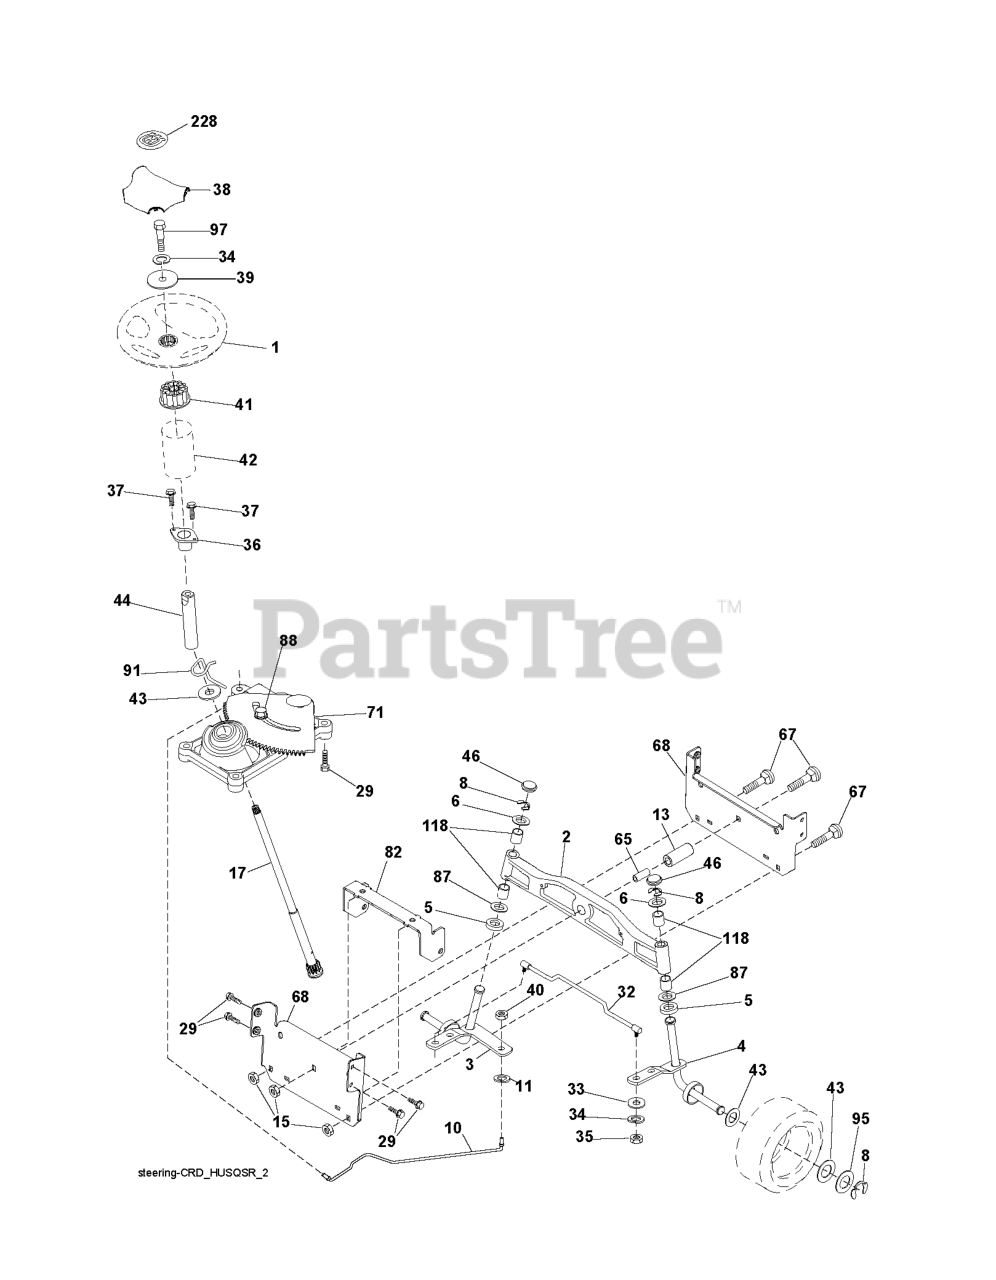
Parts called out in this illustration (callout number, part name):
1	RP WHEEL.STEER.HUSQ.PREM.OVMLD
2	AXLE ASSY FRONT
3	SPINDLE.ASM.LH.15"TIRES
4	SPINDLE.ASM.RH.15"TIRES
5	THRUST WASHER
10	DRAGLINK.15".TIRES.2001
11	WASHER, LOCK 3/8
13	TUBE, PIVOT AXLE
15	NUT
17	SHAFT STEERING SPLINE
29	SCREW, 3/8-16X3/4
33	WASHER M
34	WASHER.LOCK.HVY.HLCL.SPR.5/16
35	NUT, CROWNLOCK
36	BUSHING, STEERING
37	SCREW.TT.#10-32X.5.3/8.FLANGE
38	RP INSERT.CAP.WHL.STRG.HUSQ.
39	WASHER.11/32
40	NUT CROWNLOCK 3/8-24
41	ADAPTER, WHEEL STNG..
42	BOOT, STEERING
44	SHAFT.EXTEN.STRG.SPLINE
46	CAP.SPINDLE.BLACK
65	SPACER BRACE AXLE
67	BOLT CARRIAGE
68	BRACE.AXLE.15"TIRES
71	STEERING ASM
82	BRACKET.SUSP.CHASSIS.FRONT.15
87	WASHER, FLAT .781 X 1 1/2"
88	BOLT, SHOULDER 7/16-20
91	CLIP.STEERING
95	WASHER.HARDENED
118	BUSHING, AXLE CAST
228	DECAL.WHEEL.STRG.LGN.H
